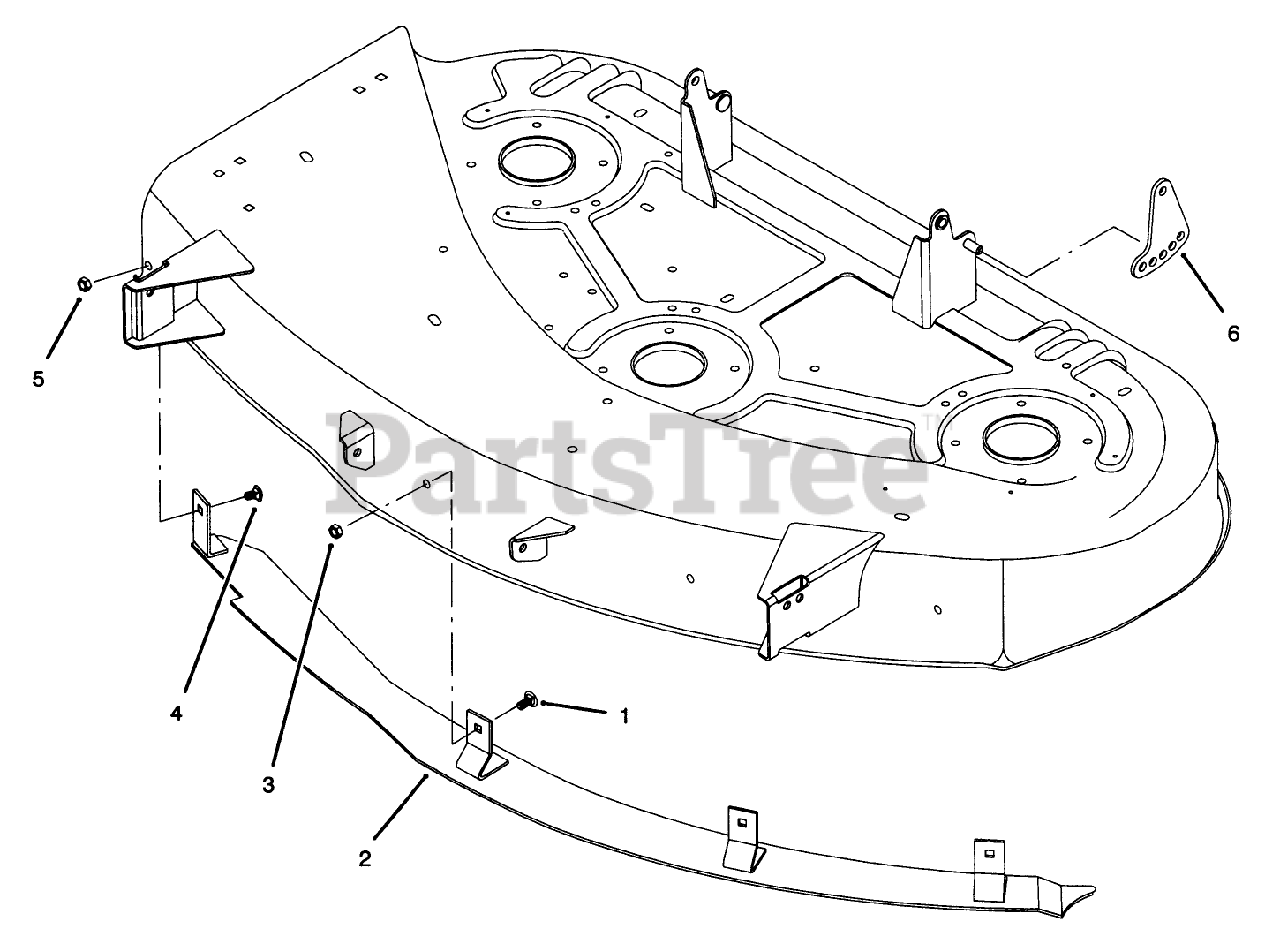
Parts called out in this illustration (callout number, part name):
1	SCREW-CARR
3	NUT-LOCK, NI
4	BOLT-CARR
5	NUT-LOCK, NI
